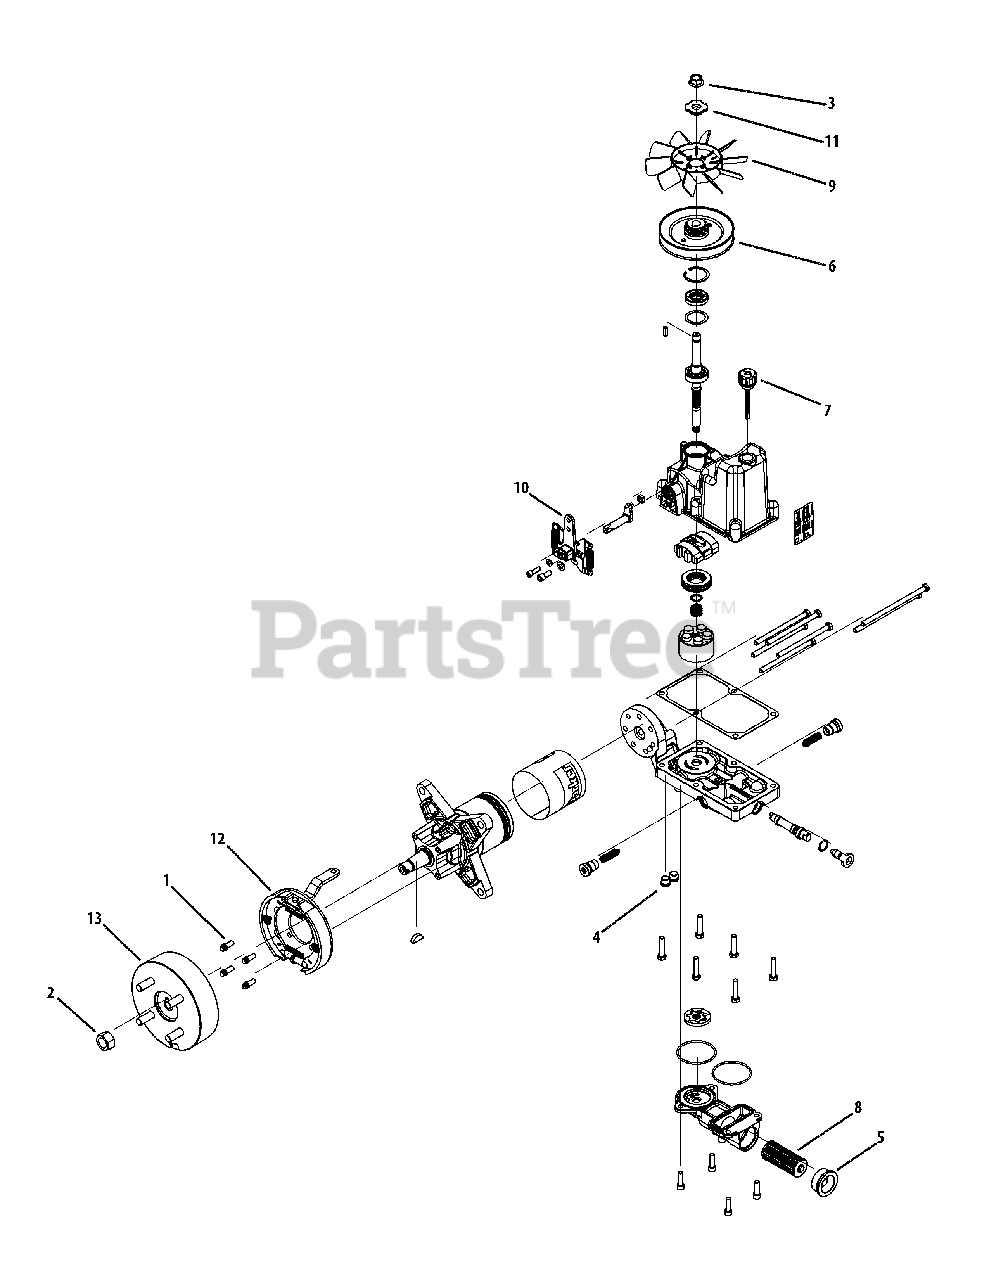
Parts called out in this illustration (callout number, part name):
1	Flange Head Screw
3	Nut, Flange 1/2-20 UNF
4	Plug, Magnetic Hex
5	Plug & O-Ring Assembly
6	Pulley (5")
7	Breather
11	Fan Spacer
12	Brake Assembly
13	Drum Assembly, 4 Bolt, 1" Shaft
